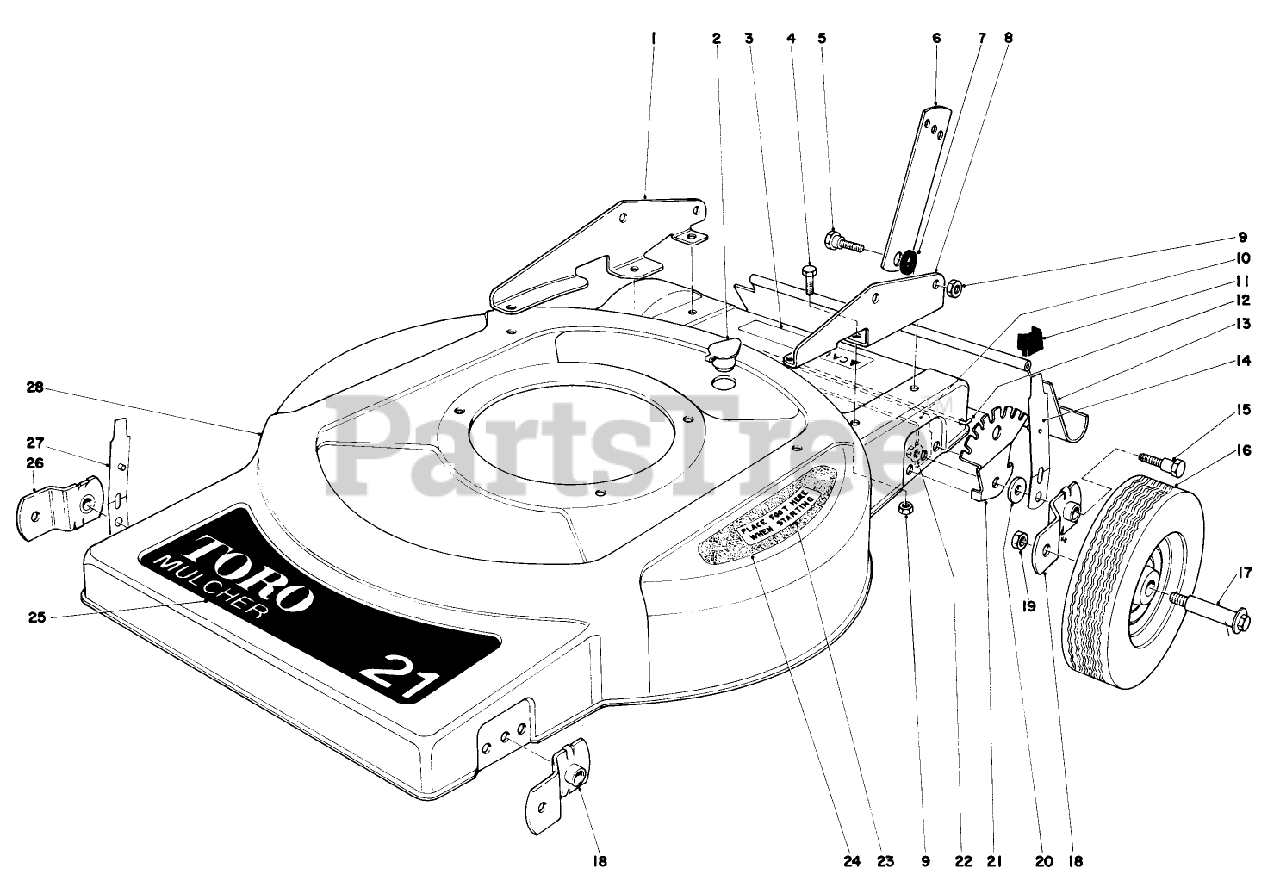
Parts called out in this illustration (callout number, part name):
2	WASHOUT PLUG
4	SCREW-HH
5	SCREW-SHOULDER
7	SPACER
9	NUT-LOCK, CONE
11	KNOB-ARM
13	SHIELD - TRAILING
15	PIVOT SCREW
18	PIVOT ARM ASM A
20	PIVOT WASHER
26	PIVOT ARM ASM
27	SPRING ARM ASM
